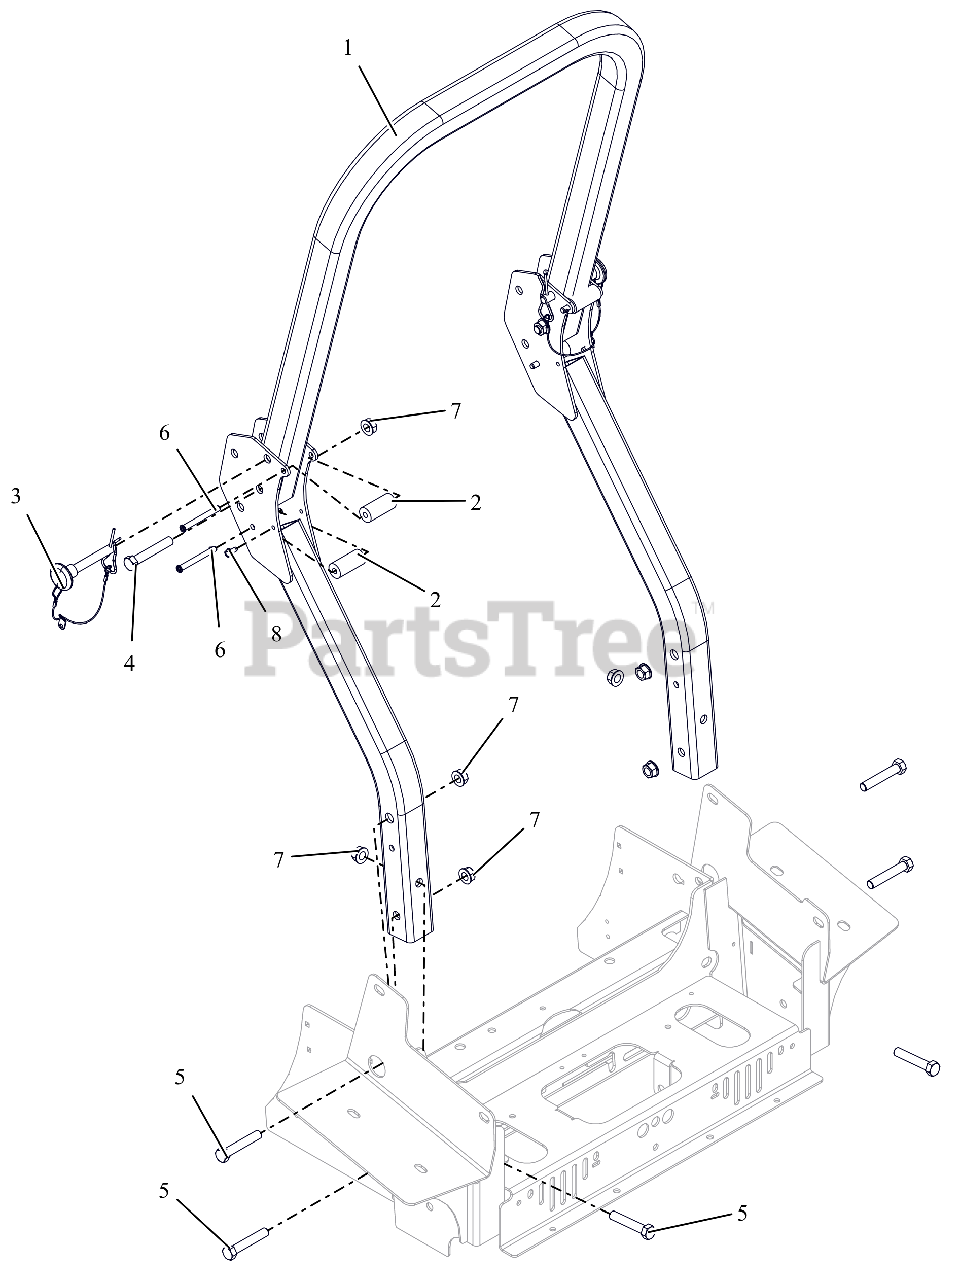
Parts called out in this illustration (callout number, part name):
1	ROPS, PT200/400 REPLACEMENT
2	BUMPER, ROPS ANTI-VIBRATION
3	PIN, ROPS W/LANYARD
4	BLT, HEX .50-13X3.00 G5 ZCC
5	BLT,HEX .50-13X2.75 G5 ZCC
6	PIN, SLIC .312 X 2.570
7	NUT-LK-CTR-FLG .500-13 GG ZCC
8	SCR-TAP .25-20X.50 HWH TR YWZ
